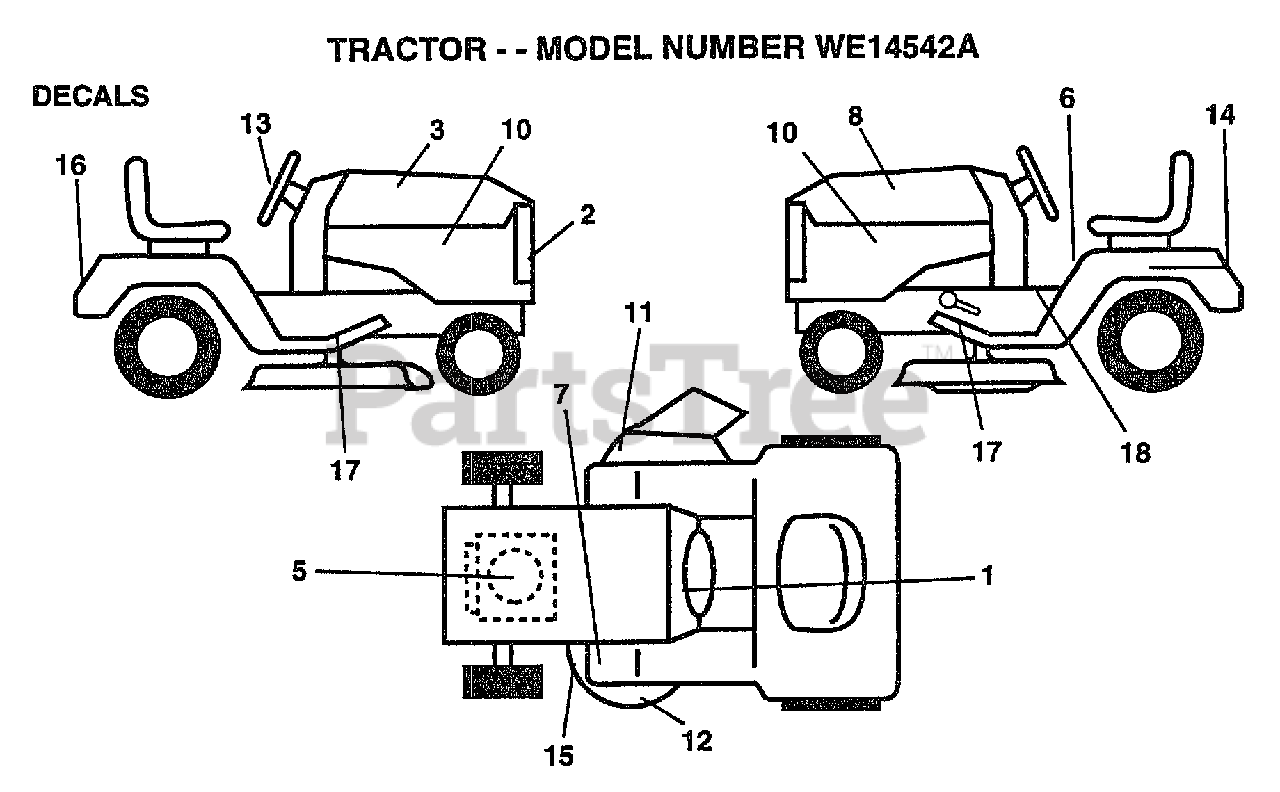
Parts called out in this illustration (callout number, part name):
1	DECAL.DASH.INSTR.
2	DECAL.GRILL
3	DECAL.HD.RH.WEED
5	DECAL, ENGINE
6	DECAL CAUTION
7	DECAL T
8	DECAL.HD.LH.WEED
10	DCL.PNL.SIDE.
11	"DECAL, WARNING"
12	DECAL.MOWER
13	DECAL.WHL.STRG.
14	DECAL
15	DECAL
16	DECAL.FENDER
17	"PAD,FOOTREST"
18	DECAL BRAK PARK
